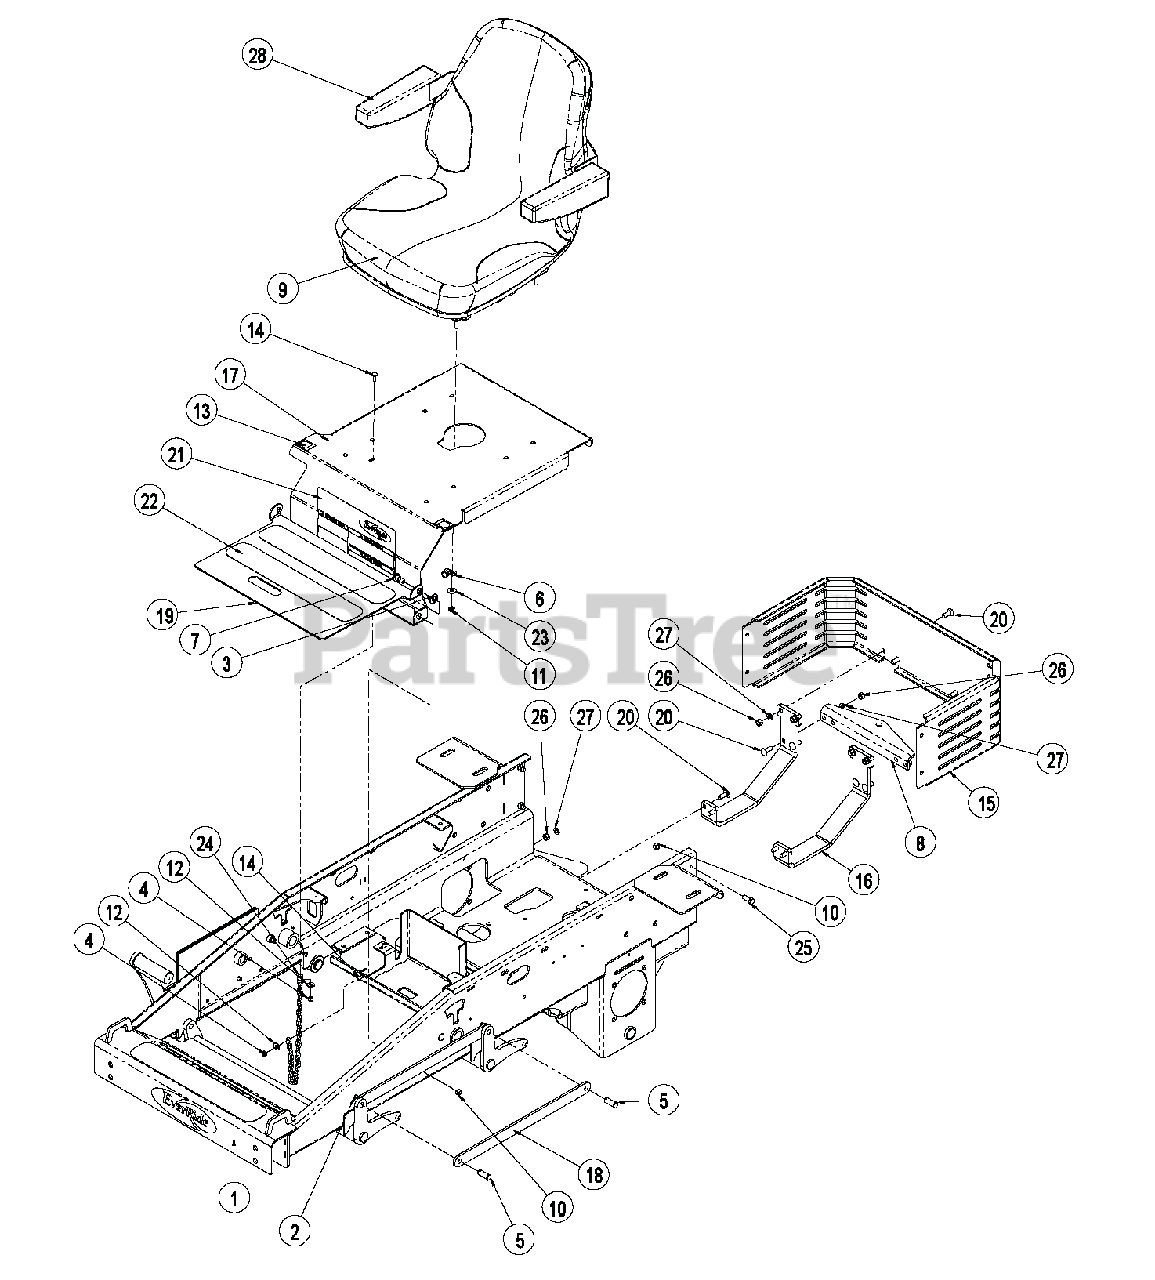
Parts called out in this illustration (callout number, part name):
1	ASSY, HORN FRM & LFT W/DCL S/O
2	RING, RUE .500 X .062 X 1.420
3	WASHER, .510X1.00X.068 NYLON
4	LOCKNUT, 1/4-20 NYLOC Y
5	PIN, CVS .500X1.25X1.02 Y
6	P-CLIP, .500 INSULATED
7	BOLT, 1/2X1.06X3/8-16 SLD 5 Y
8	PLATE, HITCH
9	SEAT, FULL SUSPENSION
10	LOCKNUT, 3/8-16 CROWN Y
11	LOCKNUT, 5/16-18 CROWN Y
12	WASHER, .250 REG FLAT
13	DECAL, PARK BRAKE
14	BOLT, 1/4-20X.750 CRG 5 Y
15	ASSY,REAR ENGINE GUARD W/DECAL
16	BRACE, BENT ARM HITCH
17	ASSY, SEAT PLATE W/DECALS S/O
18	PLATE, ARM CONNECTOR LINK
19	ASSY, FLOOR PAN W/DECALS
20	BOLT, 3/8-16X1.00 CRG 5 SN Y
21	DECAL, SAFETY GROUP
22	TAPE, TRACTION 3.00 X 17.00
23	WASHER, .313 REG FLAT Y
24	CHAIN, .148 X 27 LIINKS
25	BOLT, 3/8-16X1.00 HEX 5 Y
26	NUT, 3/8-16 STD HEX GR5 Y
27	WASHER, .375 MED SPRG LOCK Y
28	ARM REST, SINGLE S/O
